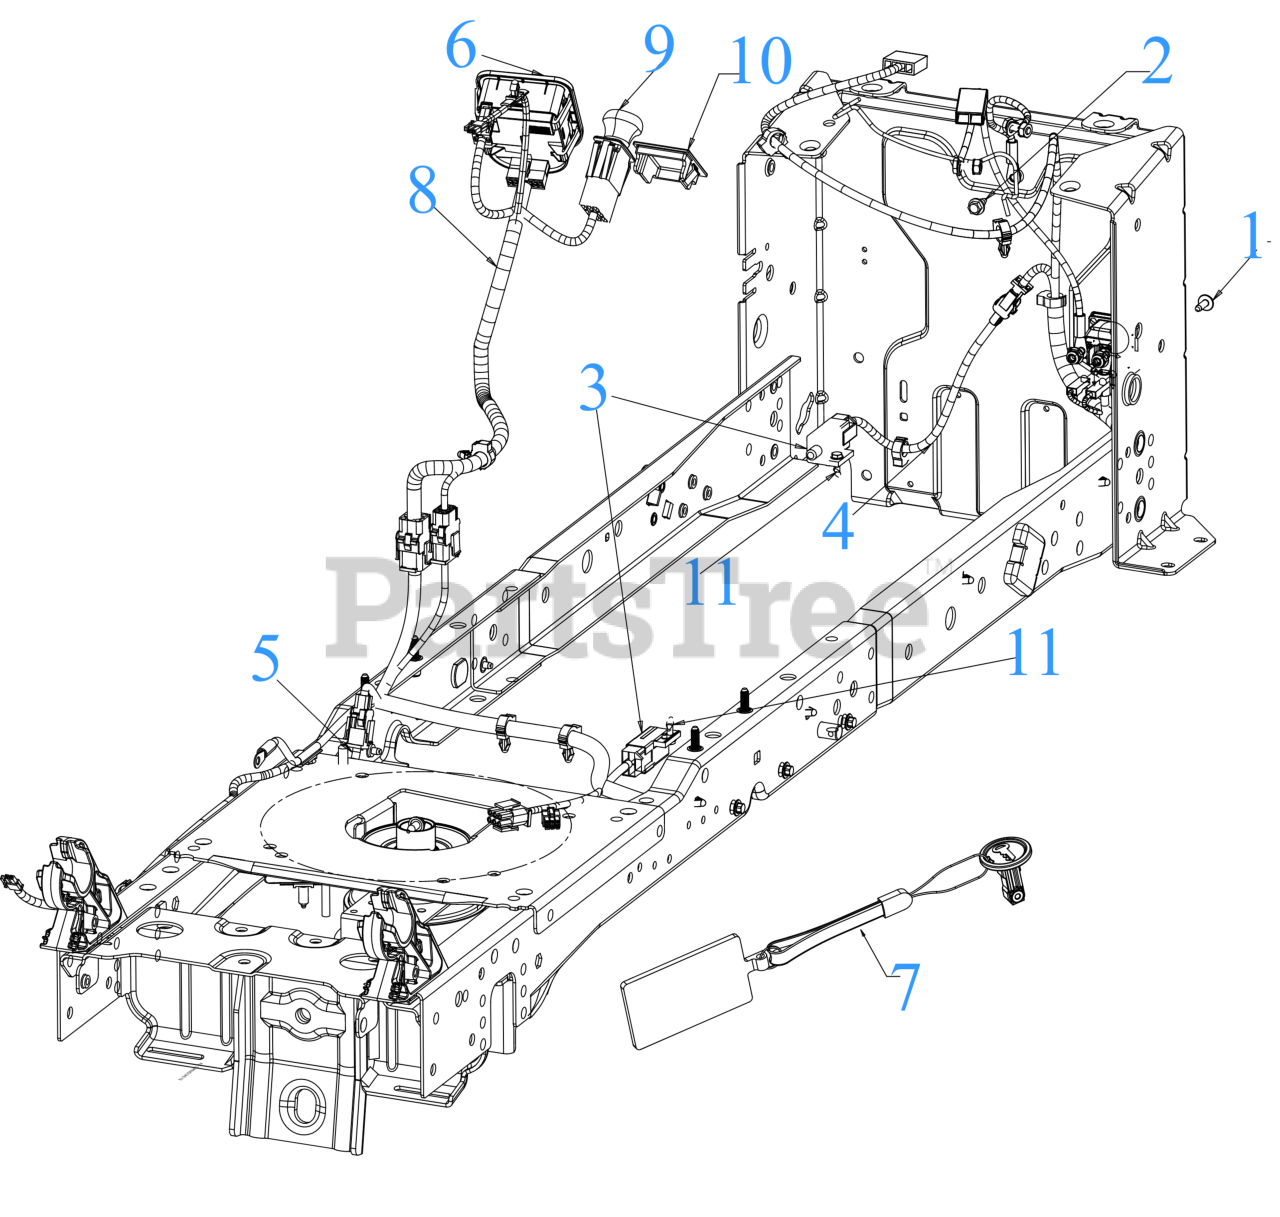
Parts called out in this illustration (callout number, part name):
1	SCREW M6-1 x .625
2	SCREW 1/4-20X.625
3	INTERLOCK SWITCH (NO/NC)
4	REVERSE HARNESS
5	CLUTCH HARNESS 11"
6	MODULE (PBS/HRMTR/SVC MNDR)
7	PBS KEY
8	MAIN HARNESS (E-PTO/PBS/EFI)
8	12V SOLENOID
9	PTO SWITCH (YELLOW KNOB)
10	DASH HOUR METER PLUG
11	SHOULDER SCREW
